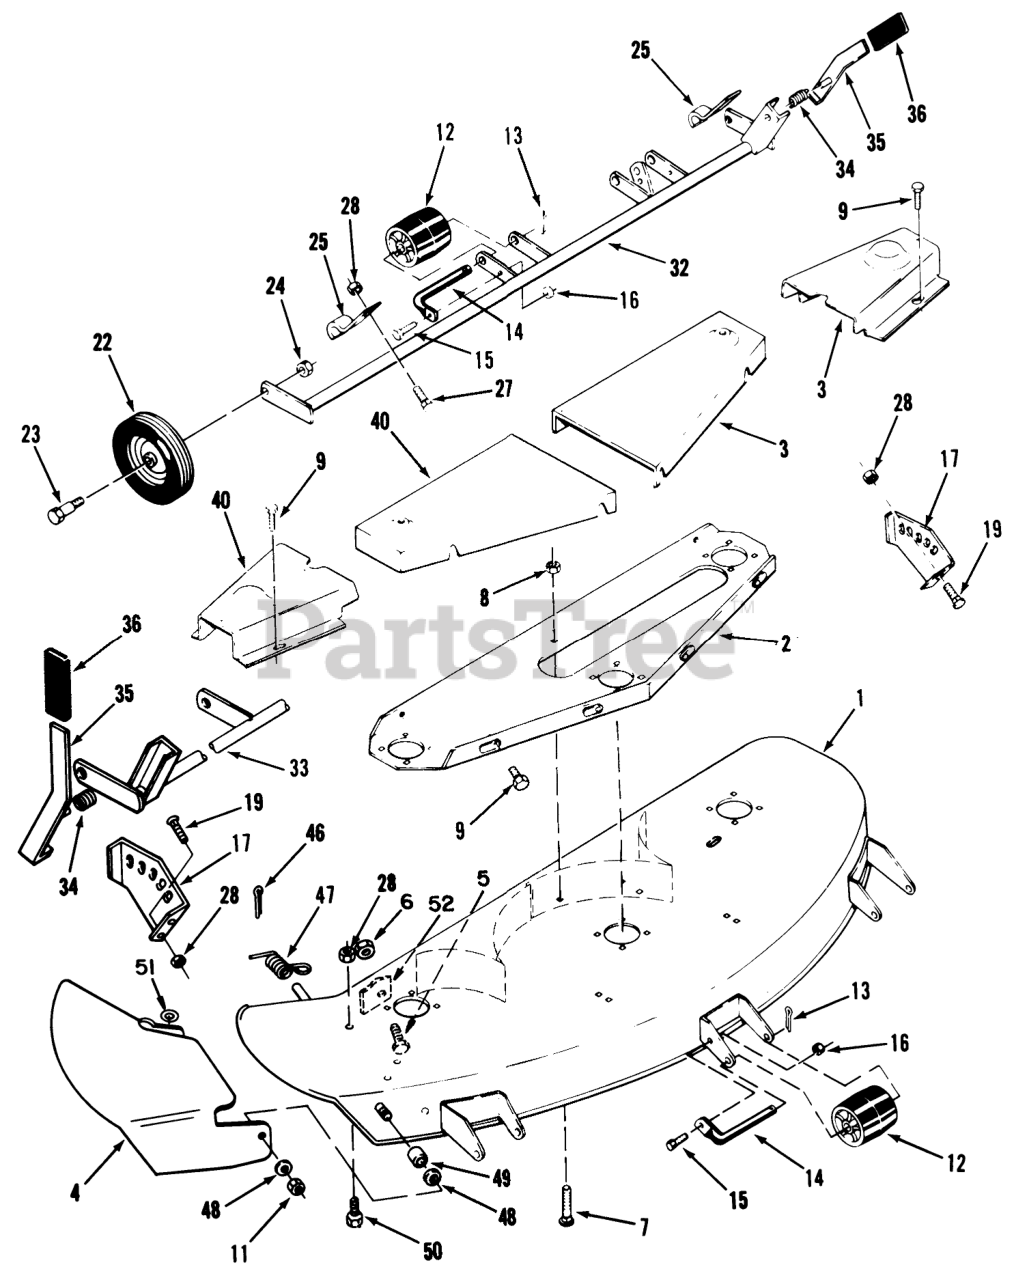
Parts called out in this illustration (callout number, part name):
1	Mower Deck 15-48SC02
1	Deck-Mower
2	Channel
3	Belt Cover LH
4	Chute Extension
5	Bolt
6	Nut
7	Bolt
8	NUT
9	Screw
9	Bolt
11	Nut
12	Roller
13	Cotter Pin
14	ROLLER-SHAFT
15	Bolt
16	Nut
17	Quadrant
19	Bolt
22	WHEEL
23	BOLT-SHOULDER
24	Nut
25	Clamp
27	Bolt
28	NUT
32	Support-Gage Wheel
33	Support-Gage Wheel
34	SPRING-COMPRESSION
35	Lever
40	Belt Cover RH
46	Pop Rivet
47	Spring
48	Washer
49	BUSHING-PIVOT
50	Bolt
51	Washer
52	Guard-Chute
